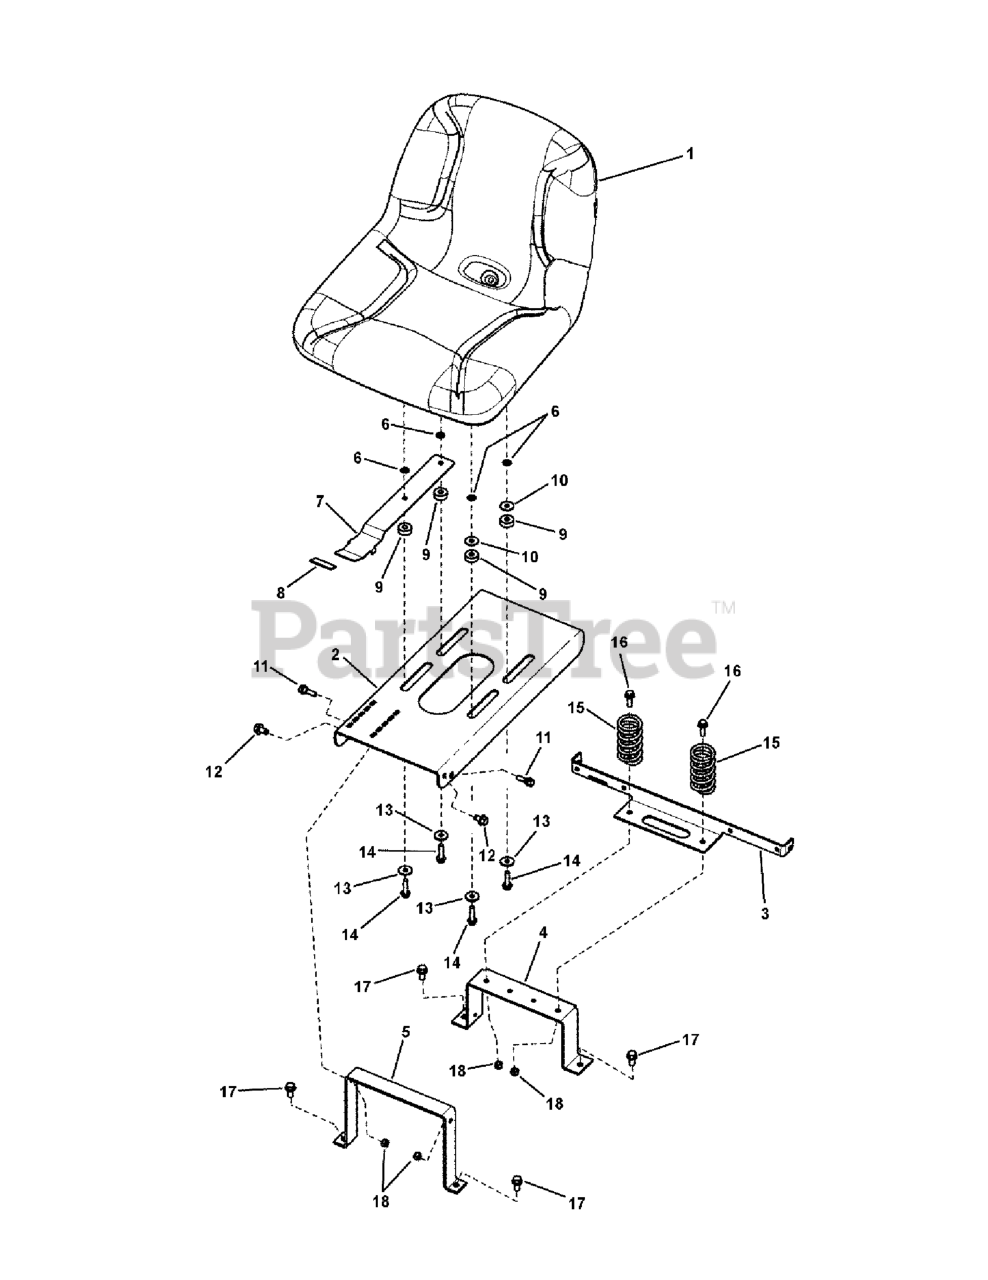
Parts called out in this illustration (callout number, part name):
1	SEAT, 15" Back
2	PLATE, Seat, Adjustable
3	BRACKET, Support, Seat & Fender
4	BRACKET, Seat Support
5	BRACKET, Seat
6	RETAINER, 5/16" Bolt, Black
7	LATCH, Seat
8	COVER, Seat Adjustment Lever
9	SPACER, Seat, Adjustable
10	FENDER WASHER, 5/16"
11	SHOULDER BOLT, 5/16-18 x 1"
12	SCREW, 3/8-16 x 5/8" Hex Washer Self-Tap
13	WASHER, 5/16" Flat (.341 ID x 1.00 OD x .13 Thick) Black
14	SCREW, 5/16-18 x 1-1/4" Hex Head Flange Lock
15	SPRING, 3.62 " Compression
16	BOLT, 5/16-18 x 1" Hex Flange Lock, GR 5, YZ
17	SCREW, 3/8-16 x 3/4" Hex Washer Self-Tap
18	NUT, 5/16-18- Nyloc, YZ
